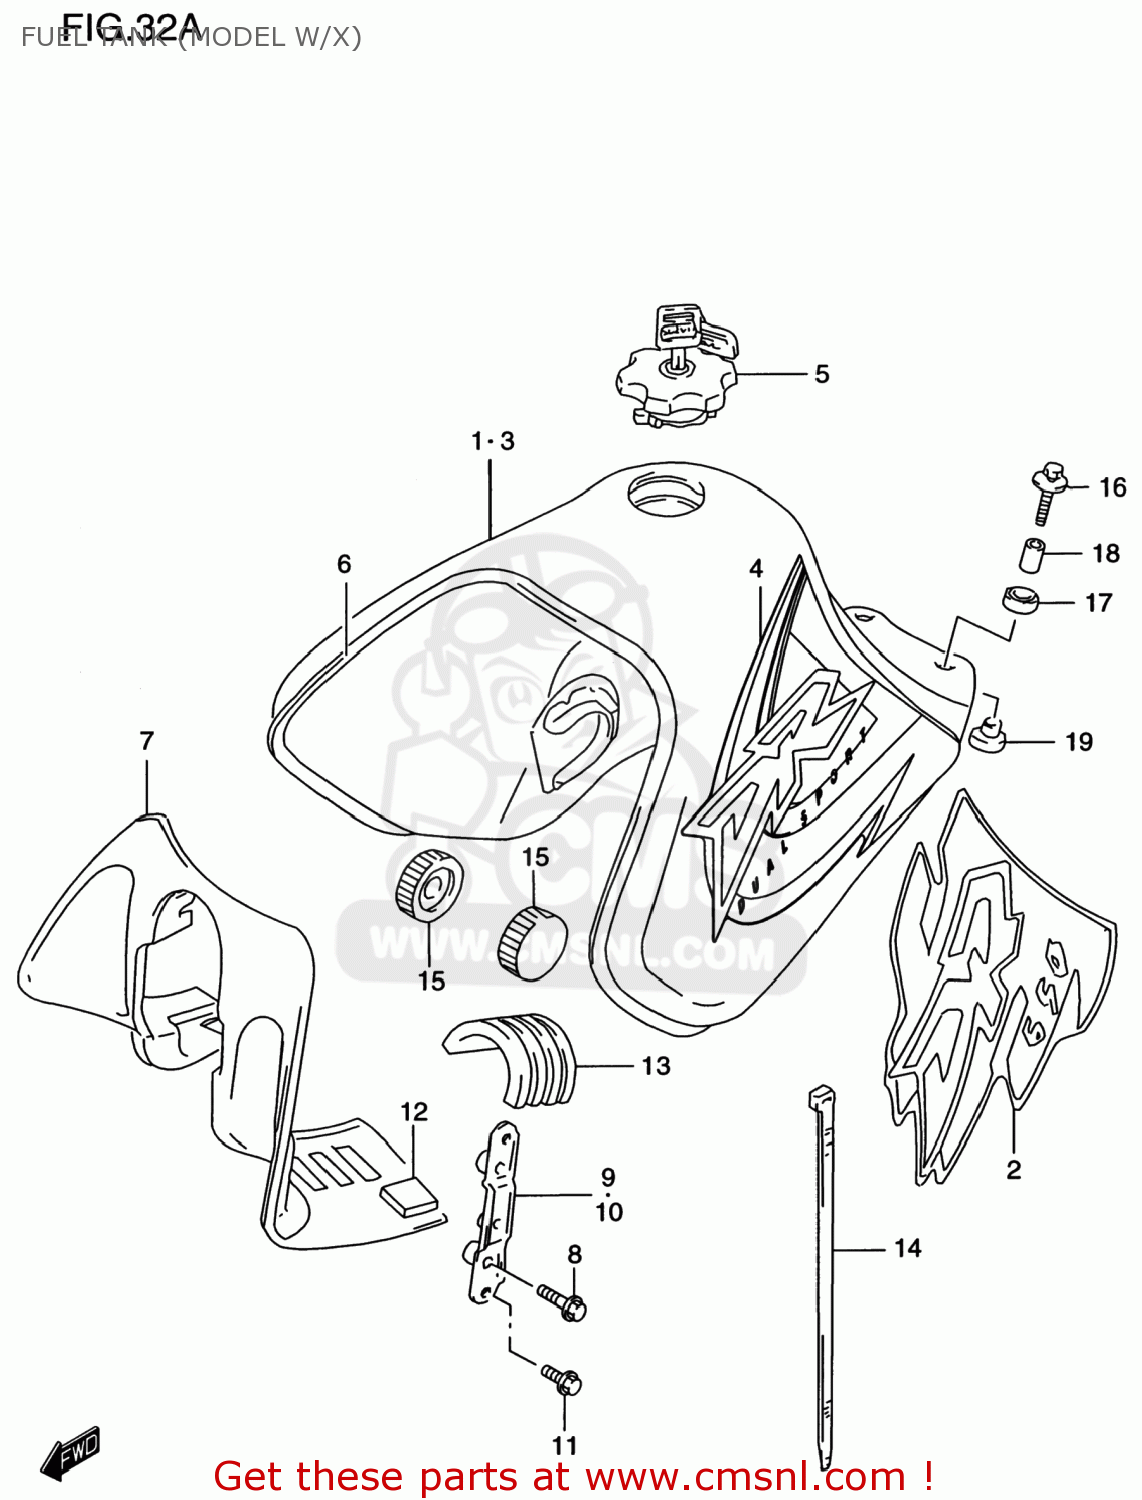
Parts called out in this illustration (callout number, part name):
1	TANK ASSEMBLY,FUEL
2	TAPE SET,FUEL TANK
3	TANK ASSEMBLY,FUEL
4	TAPE SET,FUEL TANK
5	CAP SET,FUEL TANK
6	MOLDING,FUEL TANK
7	COVER,FUEL TANK FR
8	BOLT 6X14
9	BRACKET,FUEL TANK COVER,R
10	BRACKET,FUEL TANK COVER,L
11	BOLT
12	CUSHION,HEADLAMP COVER
13	CUSHION,FUEL TANK UPR
14	CLAMP(L:250)
15	CUSHION,FUEL TANK FR
16	BOLT(6X30)
17	CUSHION
18	SPACER(6.5X9X18)
19	CUSHION
